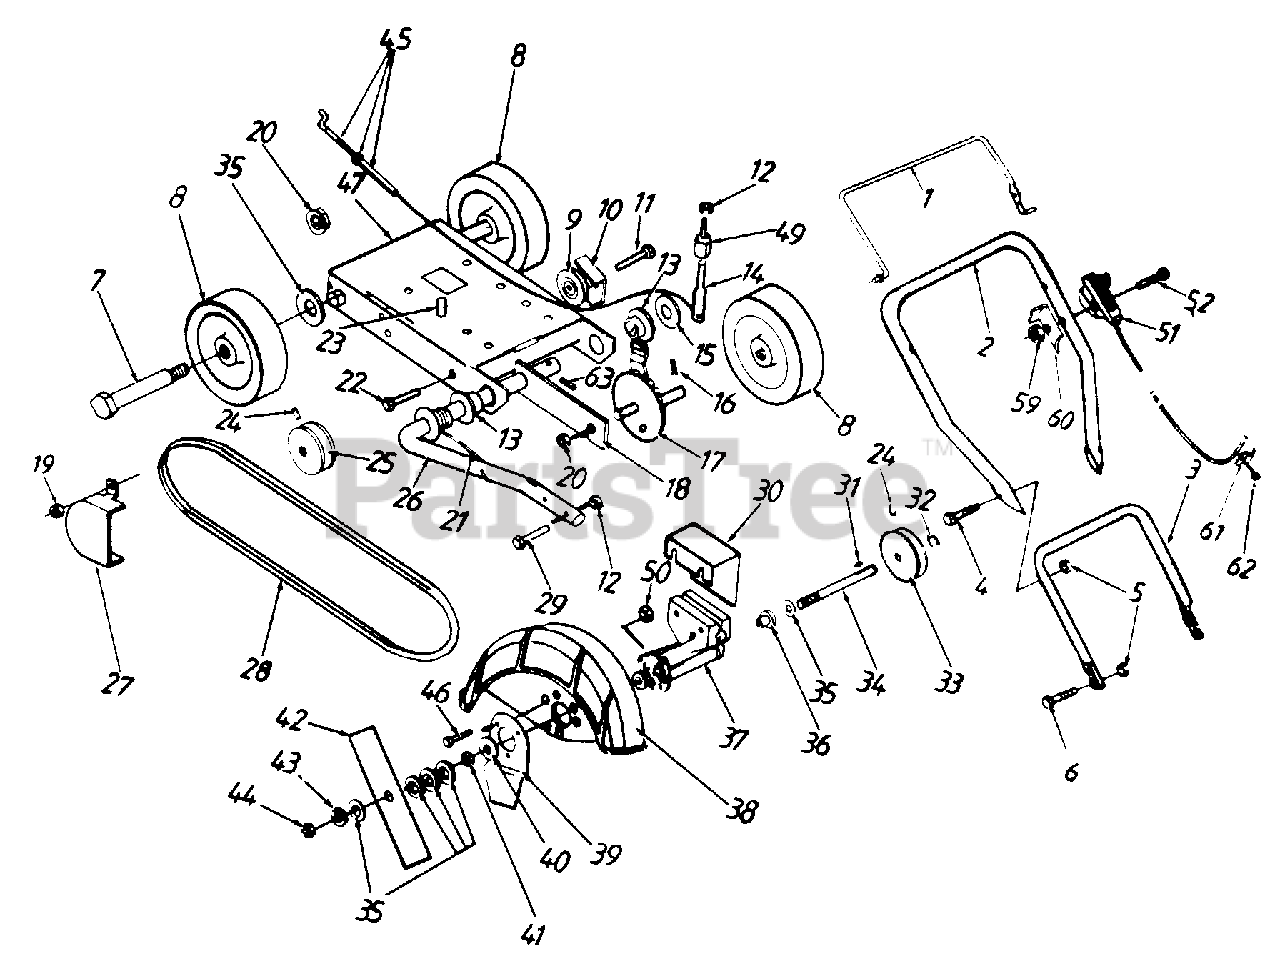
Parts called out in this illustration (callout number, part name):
1	Lever-Depth Control
2	Upper Handle
3	Lower Handle
4	Hex Bolt 5/16-18 x 1.5'
5	Hex L-Nut 5/16-18 Thd.
6	Hex Bolt 5/16-18 x .625'
7	Wheel Bolt
8	Wheel - 6'
9	Idler Pulley
10	Bracket-Idler Pulley
11	Bolt
12	Hex L-Nut 5/16-18 Thd.
13	Bushing
14	Amm-Pivot Rod
15	Flat Washer 5/8' I.D.
16	Coner Pin 1/8 x 3/4'
17	Adjustor Assembly
18	Arm-Front Wheel
19	Hex L-Nut 1/4-20 Thd.
20	Hex Keps L-Nut 3/8-16 Thd.
21	Spnng-Cutterhead
22	Hex Bolt 5/16-18 x 1'
23	Engine Bolt
24	Locking Set Scr. 5/16-18
25	Engine Pulley
26	Rod-Cutterhead
27	Belt Guard
28	V-Belt
29	Hex Bolt 5/16-18 x 1.5'
30	Belt Guard
31	Woodruff Key
32	Retaining Ring
33	Pulley-Cutterhead
34	Shaft-Cunerhead
35	Flat Washer 063- Thk.
36	Bushing-Cunerhead
37	Housing-Cutterhead shan
38	Blade Guard
39	Edge Guide
40	FlalWasher.035-Thk.
41	Heavy Hex Jam Nut 3/8-24
42	9 Replacement Blade
43	Spnng L-Wash. 3/8 I.D.
44	Hex Nut 3/8-24 Thd.
45	Cable-Depth Control
46	Hex Wash. Hd. Scr. #10-24
47	Base-Edger Frame
49	Spacer-Pivot Arm
50	Nylok Nut #10-24
51	Thronle Control
52	Hex Bolt 1/4-20 x 1.75
59	Hex L-Nut 1/4-20 Thd.
60	Stop Bracket
61	No Part Description Supplied
62	Hex Tap Scr. #8 x 3/8
63	Spiral Pin
